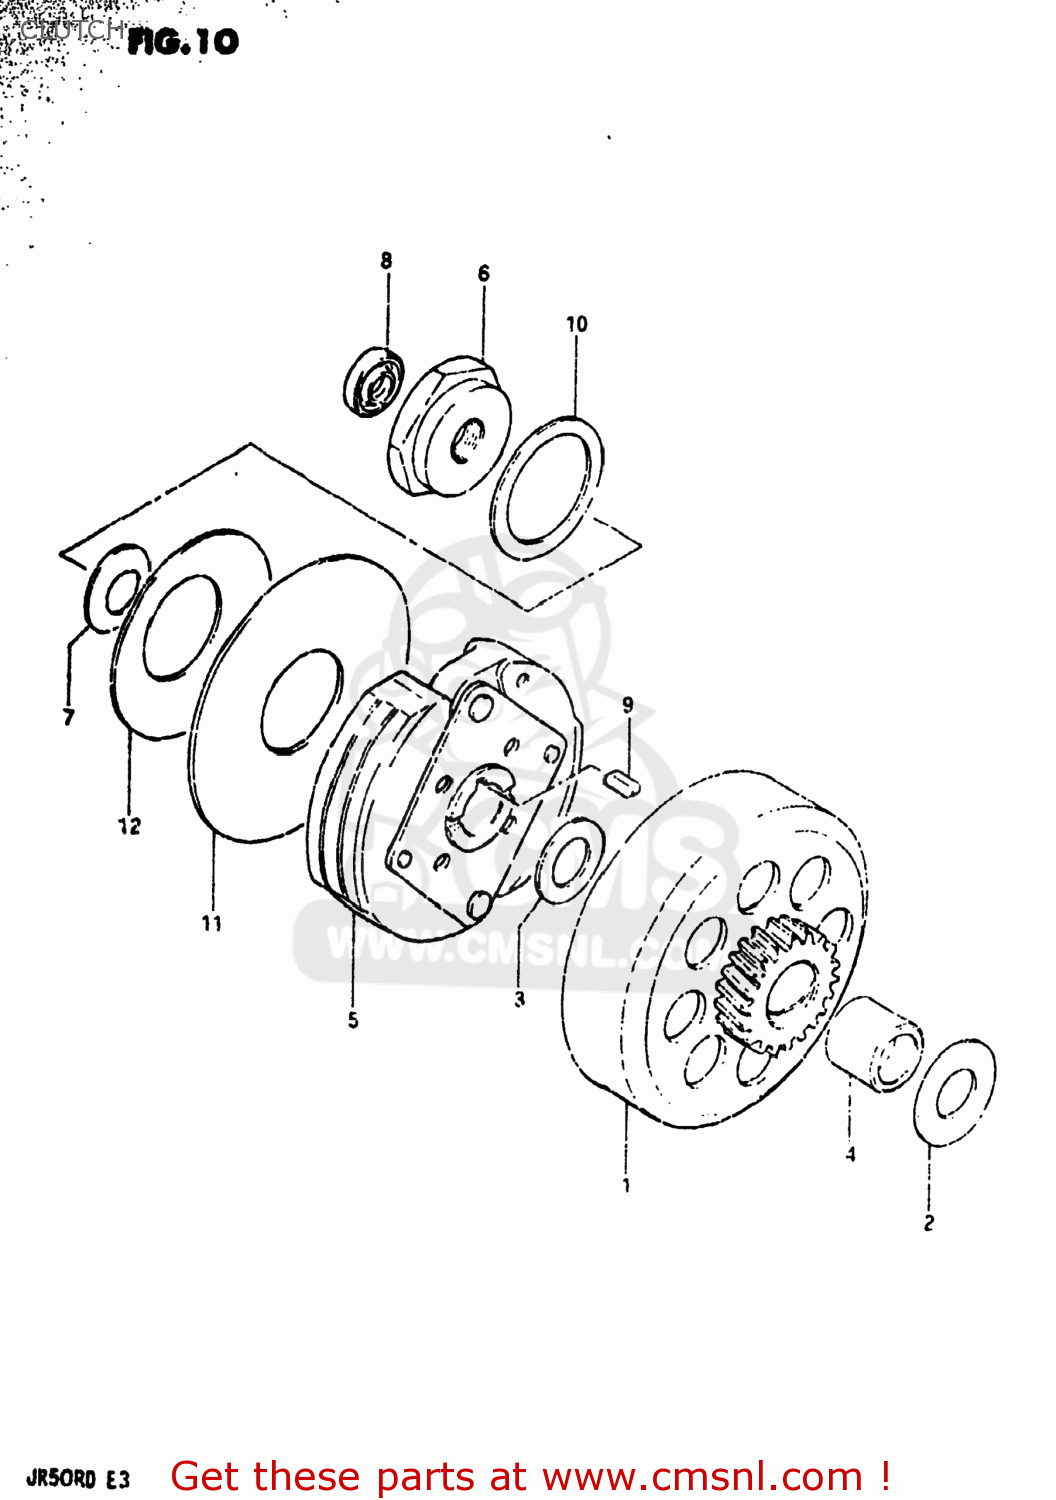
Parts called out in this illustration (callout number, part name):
1	GEAR,PRIMARY DRIVE
2	WASHER
3	WASHER(14X23X3)
4	SPACER(14X19X18)
5	CLUTCH ASSY
6	NUT
7	WASHER
8	SEAL,OIL(8X17X5)
9	KEY
10	THRUST WASHER
11	PLATE
12	WASHER
